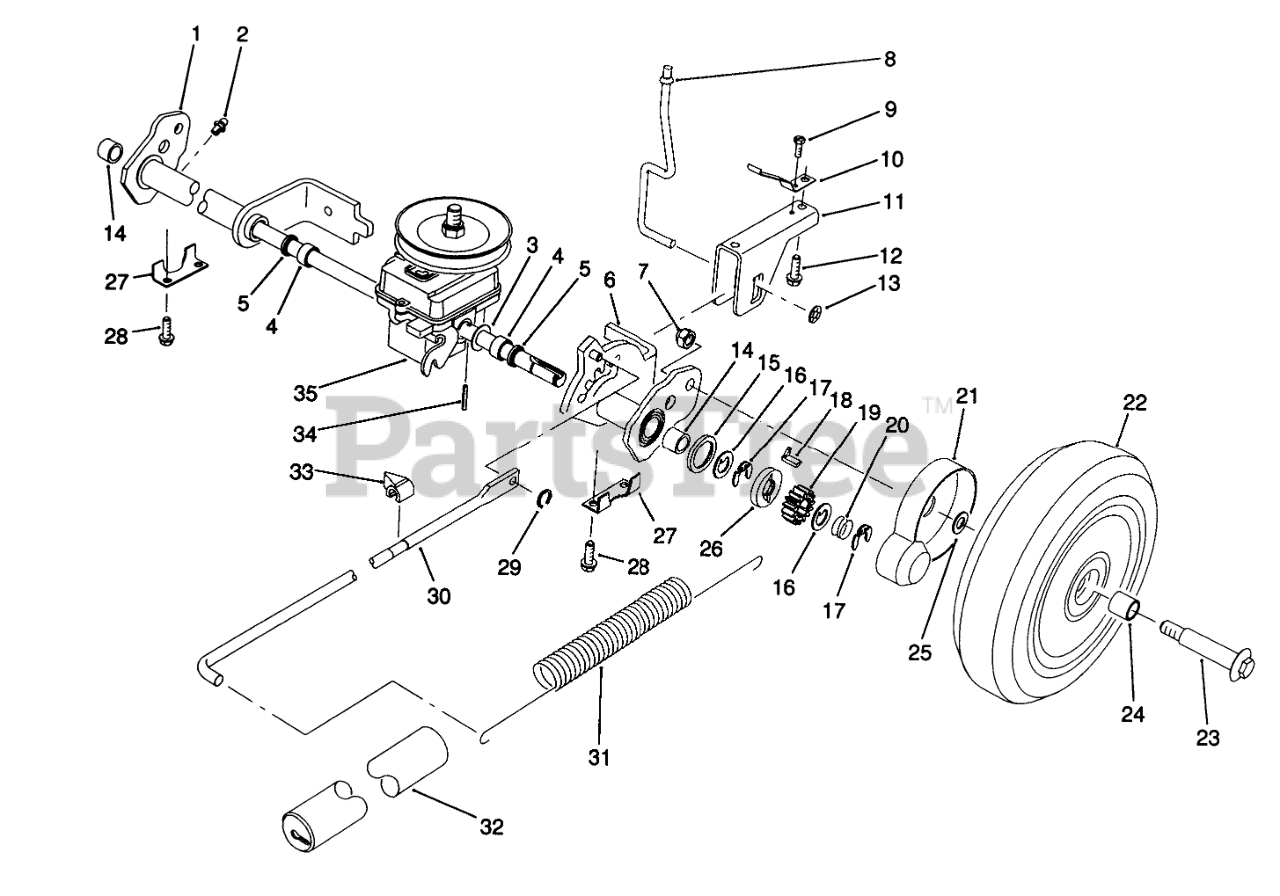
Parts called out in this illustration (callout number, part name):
1	Rear Pivot Assembly R.H. (Incl. Ref. #2, 4, 5 & 14)
2	FITTING-GREASE
3	WASHER-PLAIN
4	BUSHING
5	SEAL-OIL
6	Rear Pivot Assembly L.H. (Incl. Ref. #2, 4, 5 & 14)
7	NUT-HEX
8	TRIGGER ROD
9	SCREW 8 - 32 X 250
10	SPRING - TRIGGER RET
11	SADDLE - HOC
12	SCREW
13	PUSHNUT
14	BEARING-ROLLER
15	RING-FRICTION
16	WASHER-THRUST, KEYED
17	RING-CLIP, LOCKING
18	KEY-ROCKING, LH
19	GEAR-PINION
20	SPRING-COMPRESSION
21	COVER-WHEEL
22	Wheel, Tire & Gear Assy. (Incl. Ref. #24)
23	BOLT-WHEEL
24	BUSHING
25	SPACER-COVER, WHEEL
26	WASHER-CLUTCH
27	REAR SECURING PLATE
28	SCREW-HWH
29	GRIP RING
30	LINK ROD
31	SPRING-COUNTERBALANCE
32	COVER-SPRING
33	INDICATOR-HEIGHT OF CUT
34	COIL PIN
35	Gearbox Assembly
